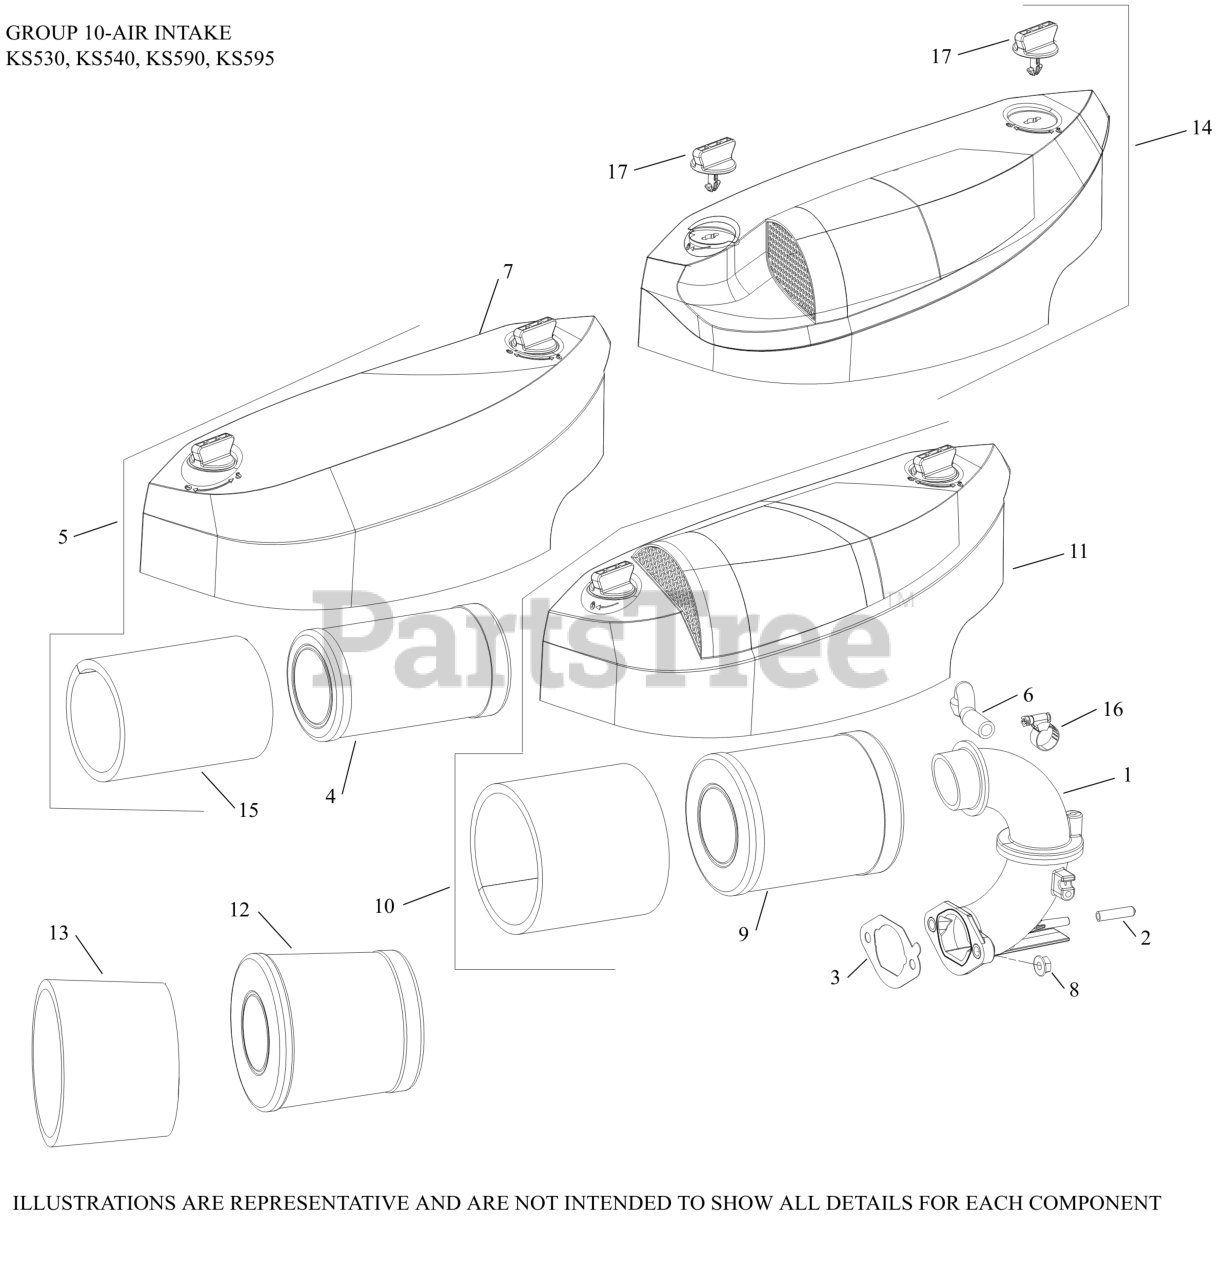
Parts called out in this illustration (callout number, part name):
1	ADAPTER, AIR CLEANER ASSY
2	CAP, MASKING
3	GASKET, CARBURETOR
4	ELEMENT, AIR FILTER
5	AIR FILTER KIT (STD)
6	HOSE, BREATHER
7	COVER, AIR CLEANER ASSY
8	NUT, FLG M6X1.0
15	ELEMENT, PRE-CLEANER
16	CLAMP, HOSE (KM)-USE 25 237 31-S
17	KNOB, AIR CLEANER COVER
